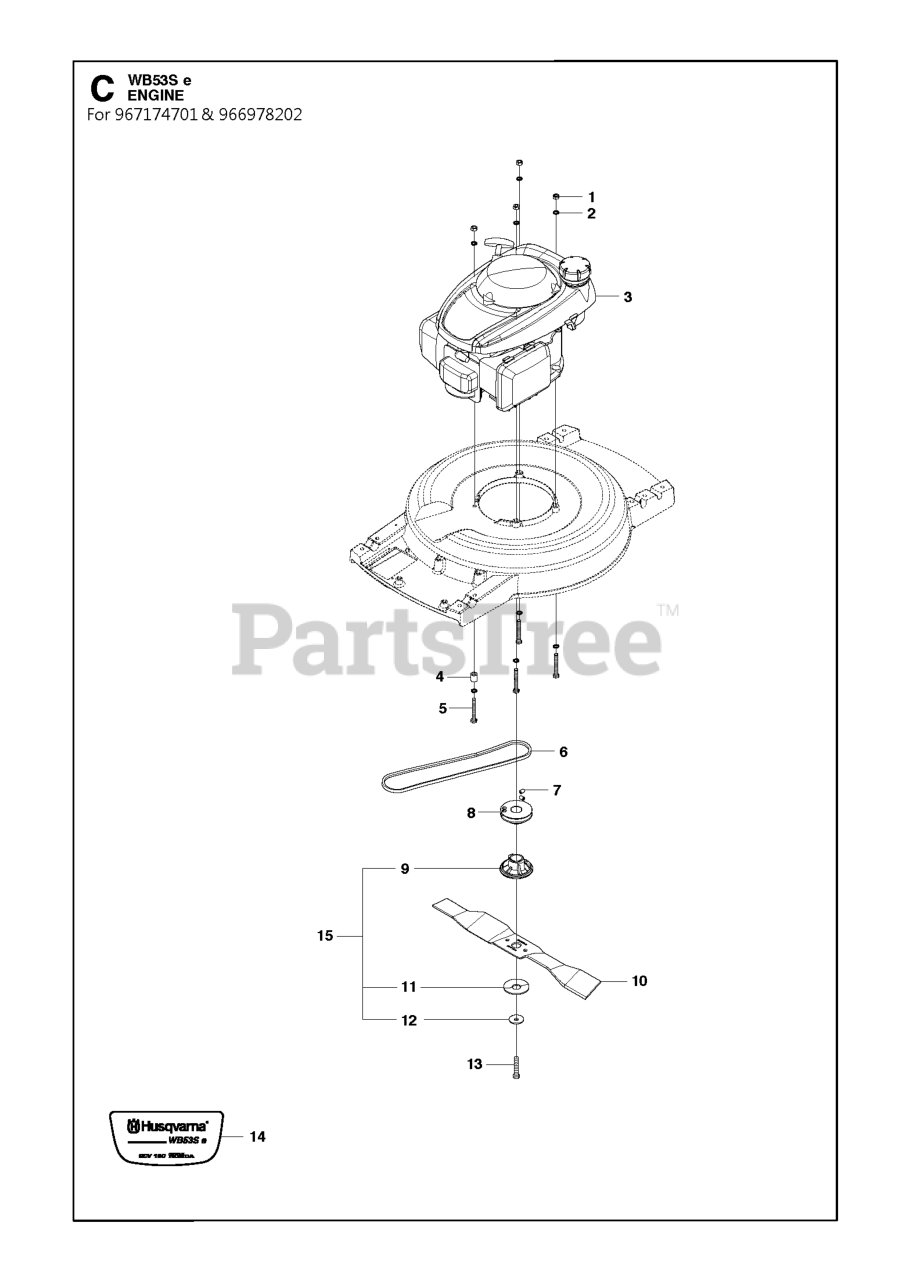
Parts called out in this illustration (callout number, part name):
1	NUT
4	SPACER M53 / M48
6	BELT
9	BLADE SUPPORT
11	SPRING M53 / M48
13	BOLT M53 / M48
